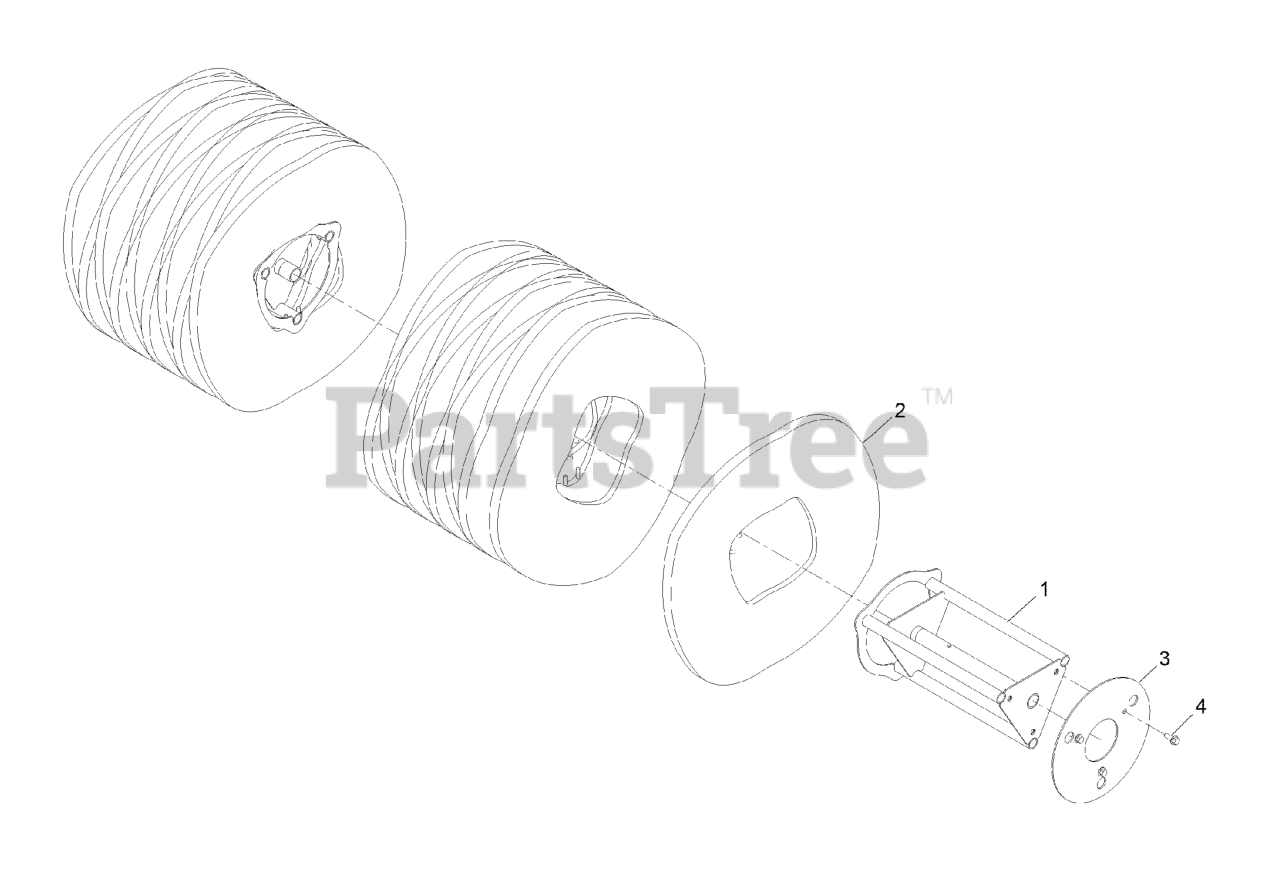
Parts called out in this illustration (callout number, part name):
1	CORE-BROOM
2	SEGMENT-POLY
3	PLATE-END, RETAINER
4	SCREW-HHF
